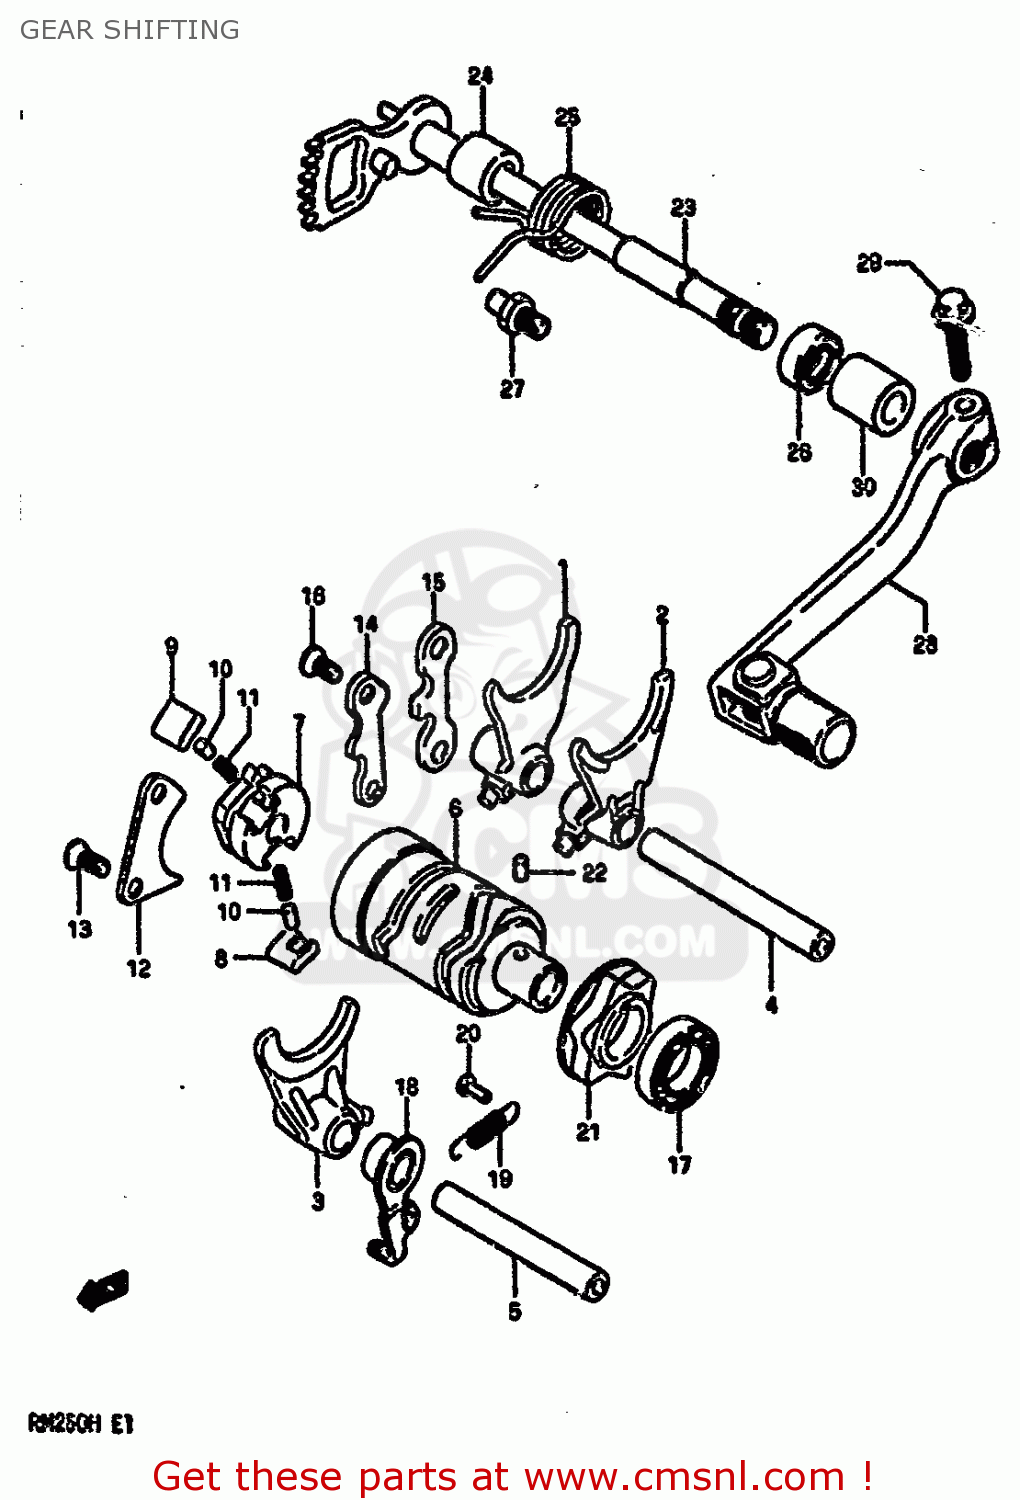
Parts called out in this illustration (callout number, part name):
1	FORK,GEAR SHIFT NO.1
2	FORK,GEAR SHIFT NO.2
3	FORK,GEAR SHIFT NO.3
4	SHAFT,GEAR SHIFT FORK
5	SHAFT,GEAR SHIFT FORK NO.2
6	CAM,GEAR SHIFT
7	GEAR,GEARSHIFT CAM DRIVE
8	PAWL,GEAR SHIFT NO.1
9	PAWL,GEAR SHIFT NO.2
10	PIN(5X8)
11	SPRING
12	LIFTER,GEAR SHIFT PAWL
13	SCREW
14	GUIDE,GEAR SHIFTING CABLE
15	GUIDE,GEAR SHIFT CAM
16	SCREW
17	BEARING
18	STOPPER,GEAR SHIFTING CAM
19	SPRING
20	RIVET
21	PLATE,GEAR SHIFT CAM STOPPER
22	PIN
23	SHAFT COMP,GEAR SHIFTING
24	SPACER(12X20X15.3)
25	SPRING
26	OIL SEAL
27	STOPPER,GEAR SHIFT CAM
28	LEVER ASSEMBLY,GEAR SHIFTING
29	BOLT
30	CUSHION 12X20X20
